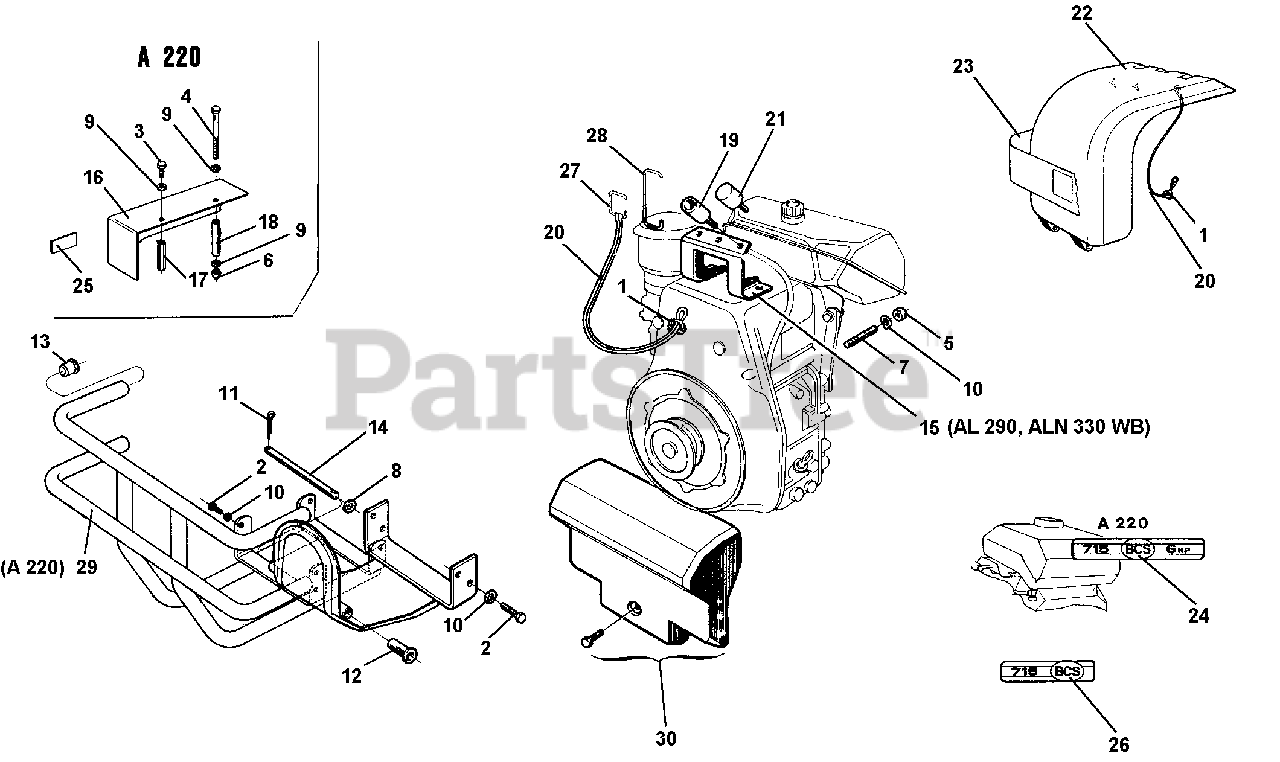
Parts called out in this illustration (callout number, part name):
1	CLAMP, CABLE 3/16
2	SCREW M8 X 16
3	SCREW M6 X 12
4	SCREW TE M6 X 65
6	NUT, SELF LOCKING M6
7	STUD M8 X 40 X 14 X 14
8	FLAT WASHER 10.5 X 21
9	WASHER, LOCK 6.4
10	WASHER, LOCK 8.4
11	PIN, COTTER Z 3 X 20 UNI 1336
14	PIN, COUPLING
15	COUPLING, TOP, AL290/ALN330WB
16	STOP SWITCH PROTECTION
18	PROTECTION SPACER
19	BUFFER, HOOD COUPLING
20	CABLE, HOOD
22	HOOD, PLASTIC, COMPLETE
23	ADHESIVE TAPE BCS 715
25	CHOKE STICKER
26	KOHLER STICKER
30	FRONT WEIGHT ASBY.,(35#)(EA)
